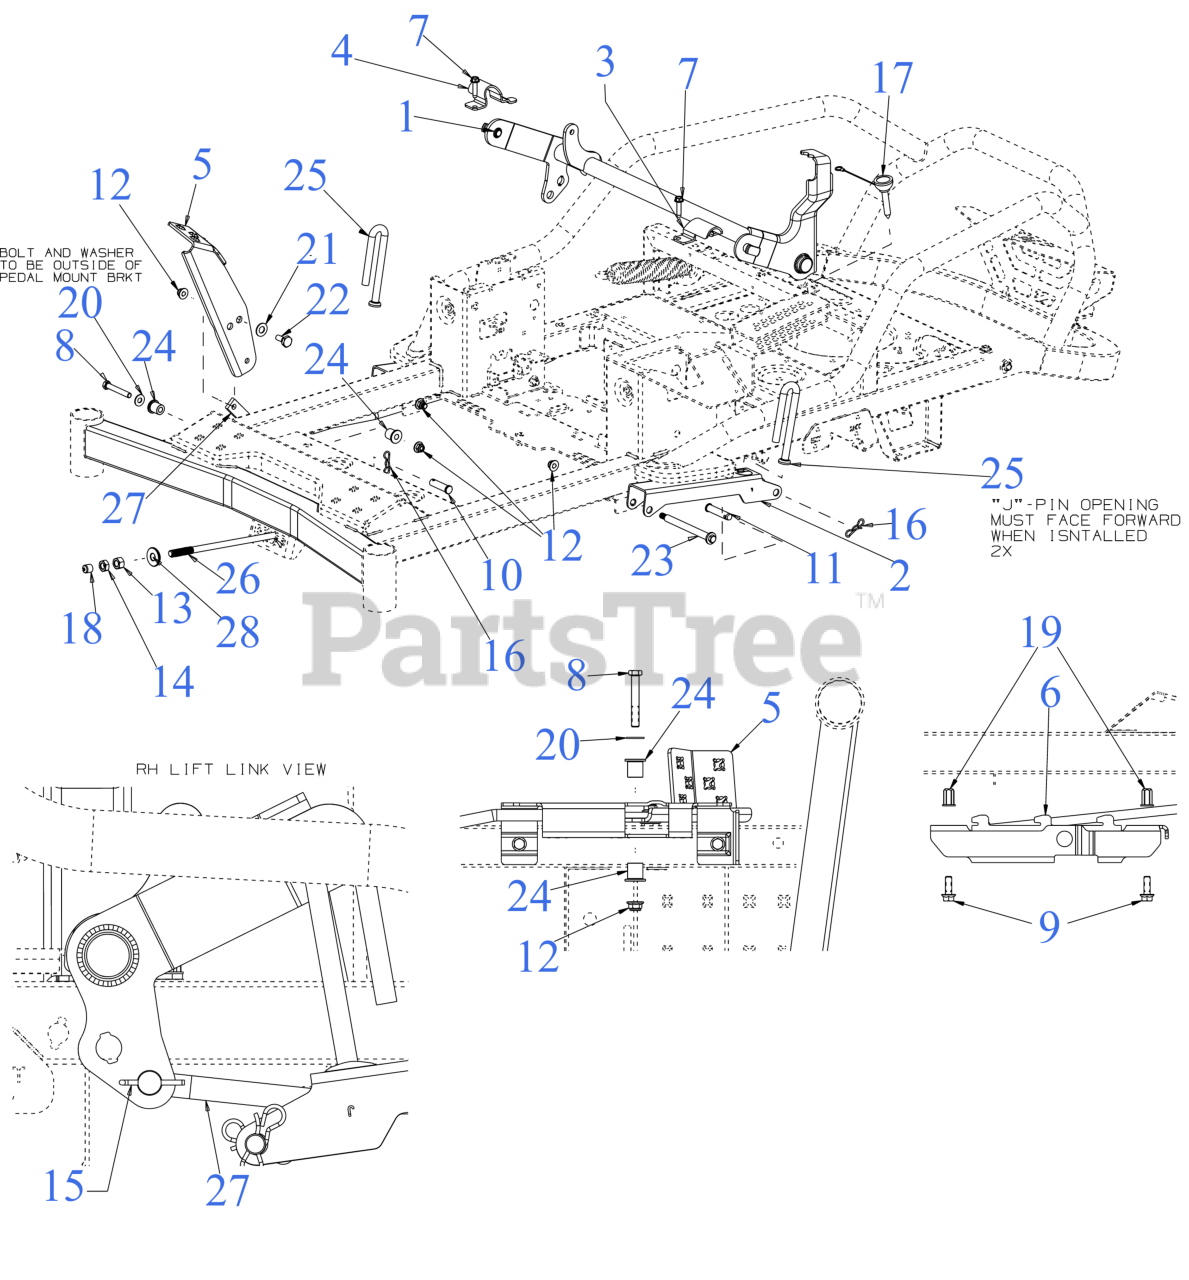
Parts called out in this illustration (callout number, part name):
1	LIFT ASSEMBLY
2	DECK LIFT LINK
3	LIFT SHAFT (RETAINER) (LH)
4	LIFT SHAFT (RETAINER) (RH)
5	DECK LIFT PEDAL
6	LIFT BRACKET
7	SCREW 5/16-18 x 1.25
8	HEX SCREW-3/8-16X2.5 GR5
9	SCREW 5/16-18 x .875 GR5 HXFLG HD
10	CLEVIS PIN .500 x 1.875
11	CLEVIS PIN .50 x 2.5
13	HEX NUT NYLOK 1/2-13
15	COTTER PIN
16	BOW TIE COTTER PIN
17	DECK LIFT KNOB
18	LIFT ROD END CAP
19	NUT RIVET 5/16-18
20	FLAT WASHER .38X.88
21	FLAT WASHER .510 x .995
22	SHOULDER SCREW
23	SHLDER SCREW .498x5.0 3/8-16
24	FLANGE BEARING (.38x.75x.77)
25	HANGER ROD
26	CONTROL ROD (FRONT)
28	DECK LIFT PIVOT CUP
